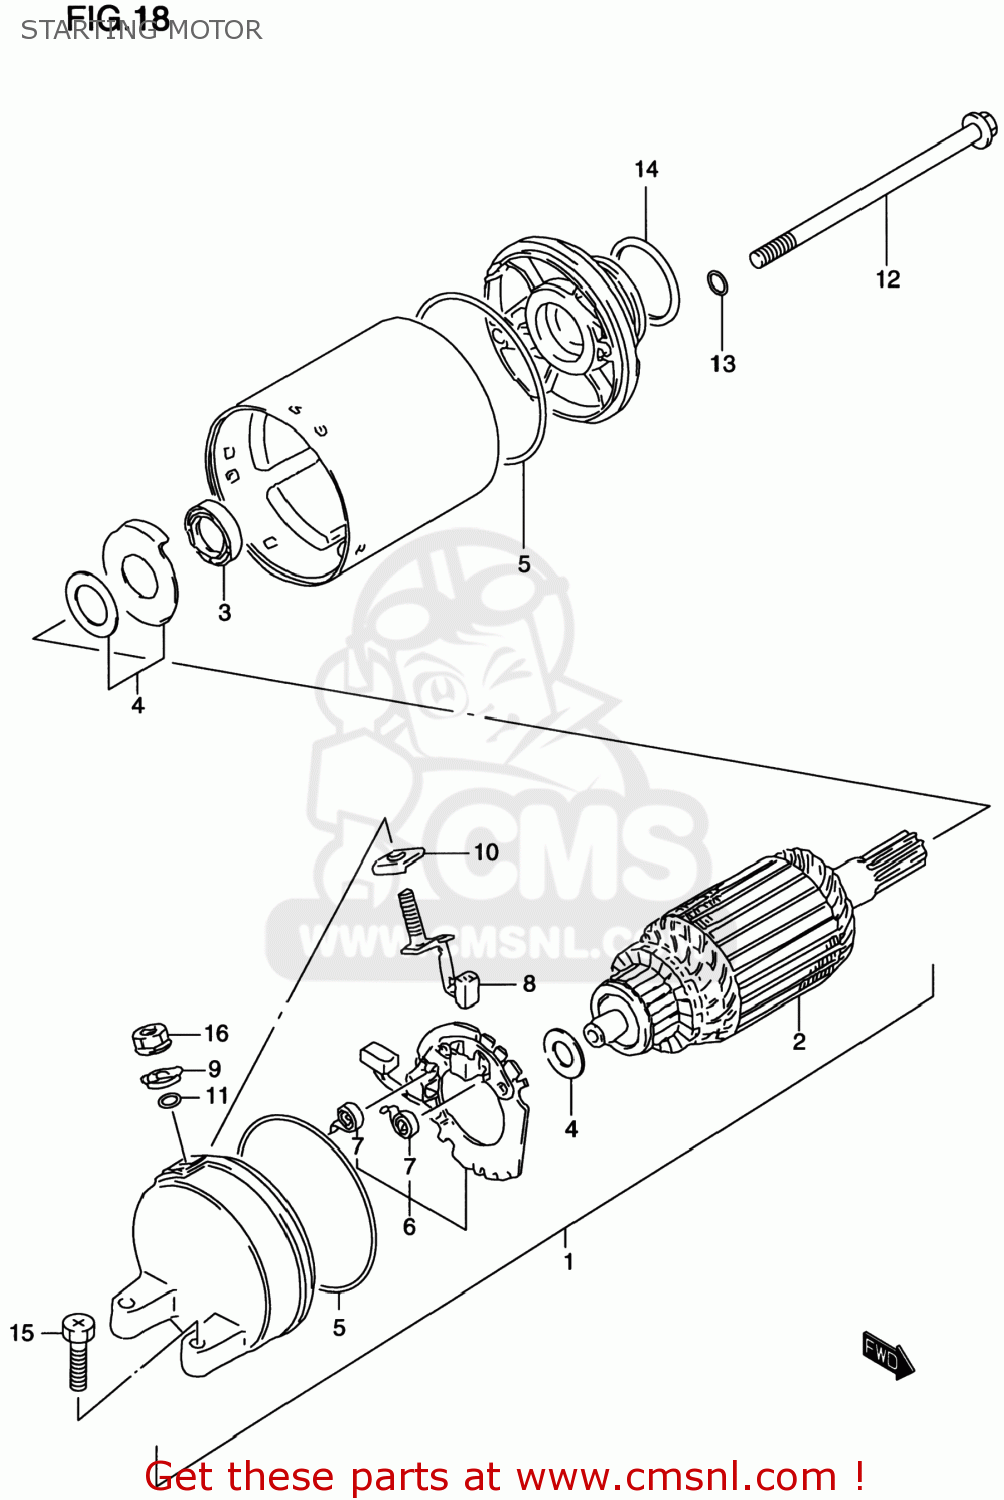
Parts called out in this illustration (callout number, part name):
1	MOTOR ASSEMBLY,STARTING
2	ARMATURE
3	SEAL,OIL
4	SHIM SET,STARTING MOTOR
5	O RING
6	HOLDER,BRUSH
7	SPRING
8	BRUSH SUB ASSY,STARTING MOTOR
9	BUSHING
10	BUSH,B
11	O RING
12	BOLT
13	O RING
14	O RING(D:3,ID:24.5)
15	SCREW (6X25)
16	NUT
